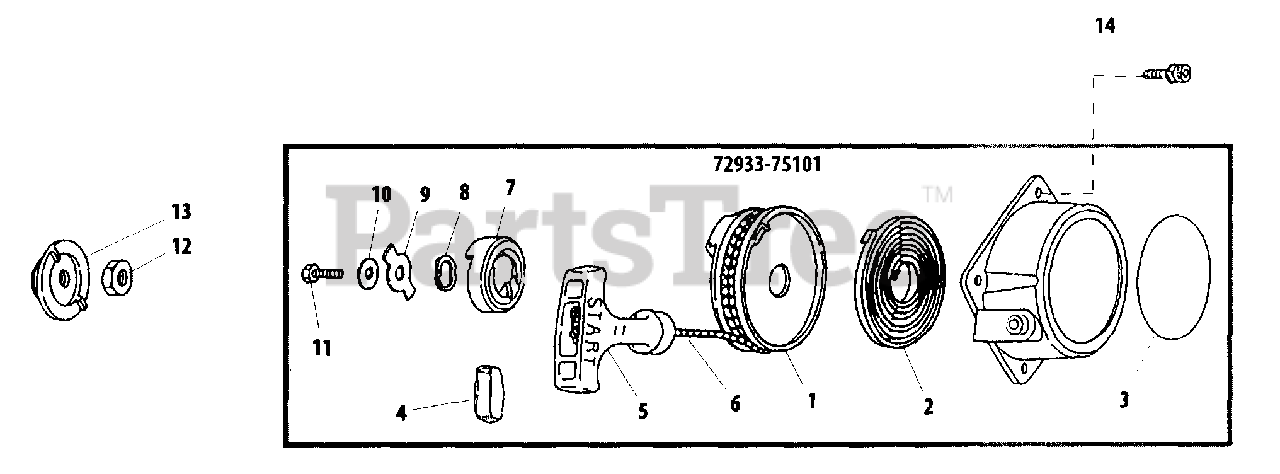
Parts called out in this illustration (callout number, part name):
1	REEL, ROPE
2	SPRING, REWIND
3	LABEL - IDENTIFICATION
4	RETAINER, ROPE
5	HANDLE
6	ROPE, STARTER
7	PAWL, STARTER
8	WASHER - SPRING
9	RETAINER
10	WASHER - 5
11	SCREW - 5
12	NUT - 8
13	PAWL
14	SCREW - 4X12
72933-75101	STARTER ASSY
